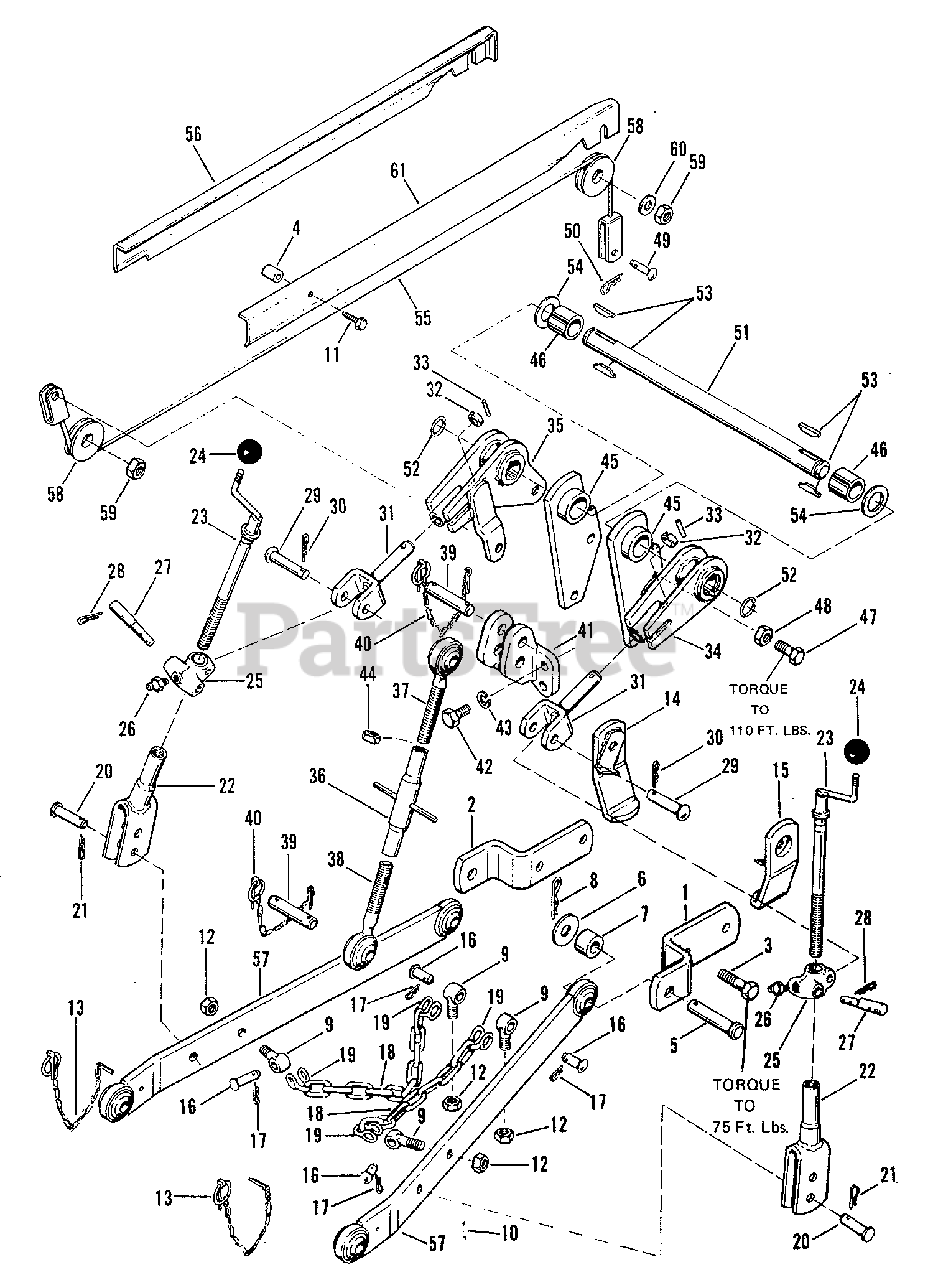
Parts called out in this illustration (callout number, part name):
1	STRAP, Pull Link, R.H.
2	STRAP, Pull Link, L.H.
3	CAPSCREW, Hex, 1/2"-13 x 2" Lg.
8	CLIP, Hair Pin
9	BOLT, Eye
10	PIN, Cotter, 1/4" x 1-1/2" Lg.
11	SCREW, Self Tapping
12	NUT, Hex, Lock, 1/2"-20
13	RING, Retaining
14	RUB BAR ASSEMBLY, L.H.
15	RUB BAR ASSEMBLY, R.H.
16	PIN
17	CLIP, Spring
18	CHAIN, (8 Links)
21	CLIP, Hair Pin
22	CLEVIS ASSEMBLY
23	LINK ASSEMBLY
26	FITTING, Grease
28	CLIP, Hair Pin
30	CLIP, Hair Pin
31	CLEVIS ASSEMBLY
34	LIFT ARM ASSEMBLY, R.H.
35	LIFT ARM ASSEMBLY, L.H.
36	UPPER LINK ASSEMBLY
37	STUD ASSEMBLY, R.H.
38	STUD ASSEMBLY, L.H.
40	RING, Retaining
41	LINK, Upper Support
42	CAPSCREW, Hex, 7/16"-14 x 1-1/4" Lg.
43	LOCKWASHER, 7/16"
44	NUT, Hex, Full
45	SUPPORT ASSEMBLY
47	CAPSCREW, Hex, 1/2"-13 x 1-1/2" Lg.
50	CLIP, Hair Pin
51	SHAFT, Rock
52	RING, Retaining
55	CABLE ASSEMBLY
56	GUARD, Wire, L.H.
57	PULL LINK ASSEMBLY
59	NUT, Hex, Lock, 1/2"-13
60	WASHER, Plain, 7/16"
61	GUARD, Wire R.H.
